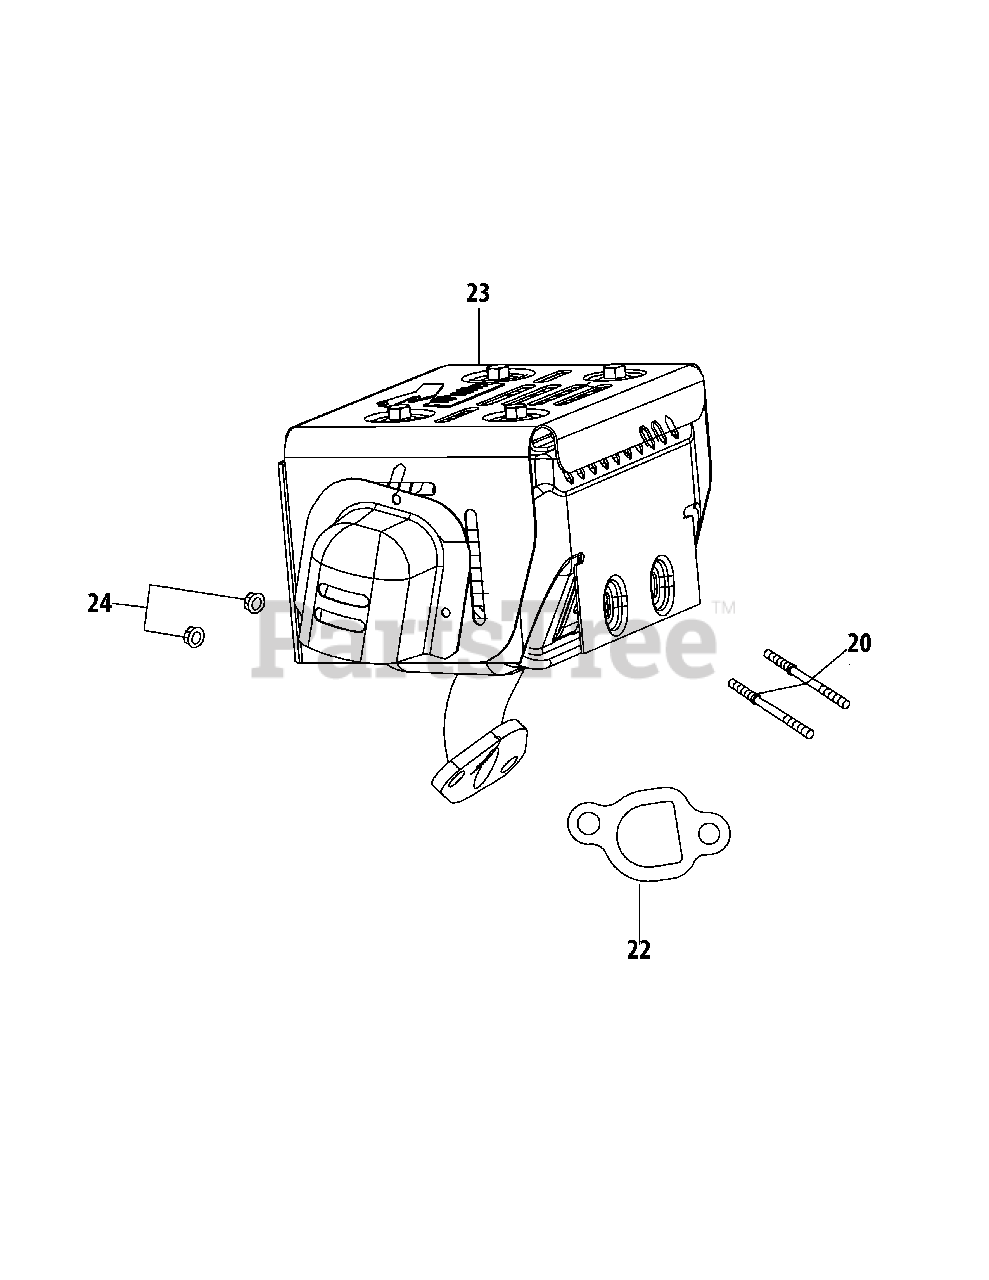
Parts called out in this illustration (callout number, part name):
20	Stud, M8×34, Exhaust
20	Muffler Stud Assembly
22	Muffler Gasket
